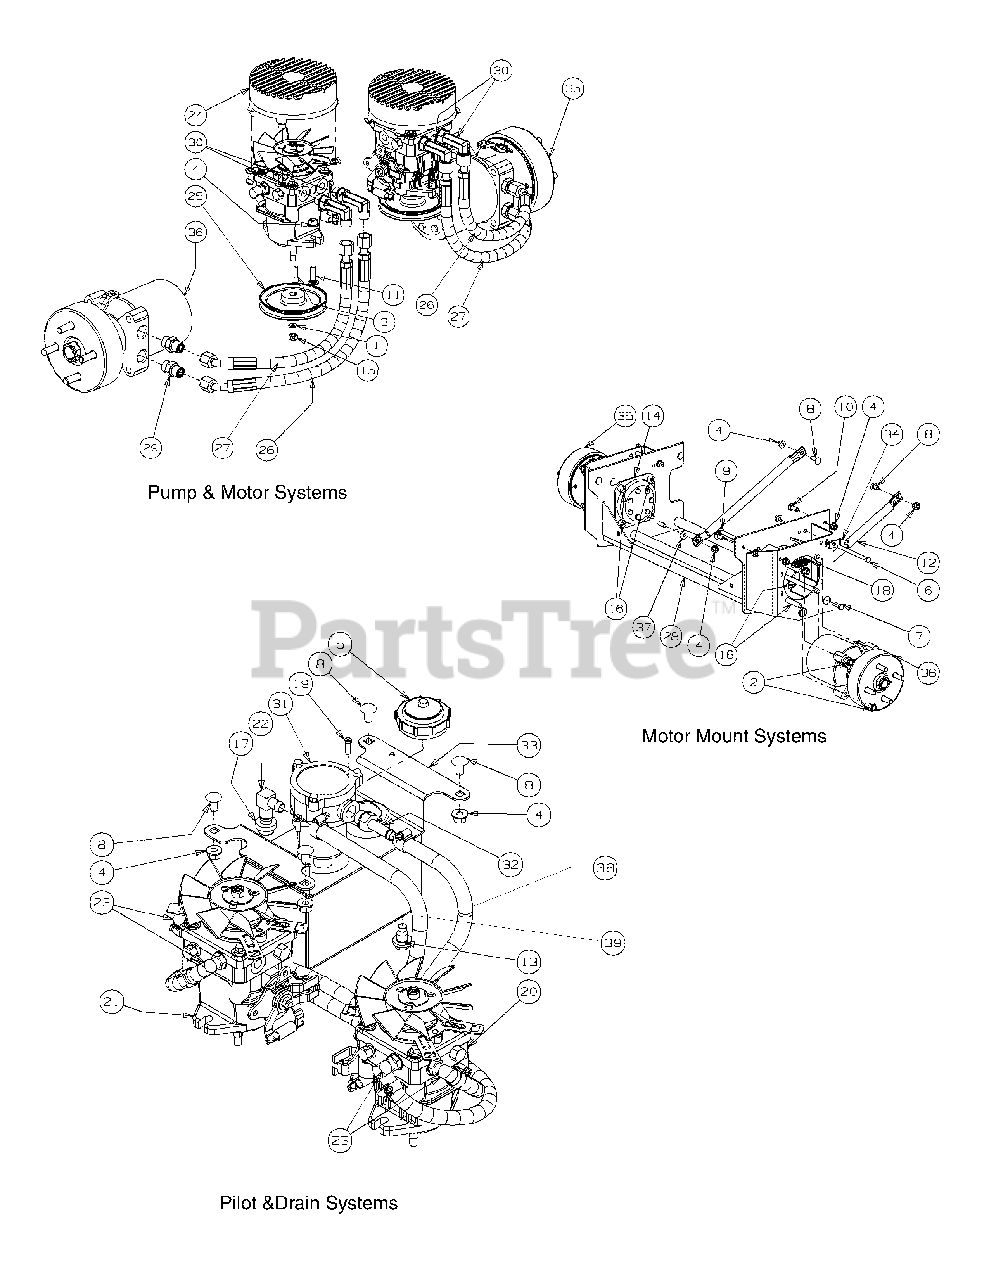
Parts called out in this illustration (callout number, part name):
1	Hose Clamp, 1/2
2	Lock Nut, Nylon Insert, 1/2-13
3	Key, 3/16" x 7/8"
4	Flange Lock Hex Nut, 3/8-16
5	Cap, Hydro Oil Tank
6	Hex Cap Screw 3/8-16 x 4.50
7	Hex Cap Screw, 3/8 -16 x 1.25
8	Carriage Bolt, 3/8-16 x .75 LG.
9	Carriage Bolt, 3/8-16 x 5.00
10	Carriage Bolt, 3/8-16 x 1
11	Carriage Screw, 3/8-16 x 1.25
14	Hydro Wheel Motor Backup Plate
15	Hex Nut, 3/8-24
16	Socket Head Capscrew, 1/2-13; 6-1/2
17	Grommet Fitting, .54 ID x .78 OD
18	Spring Extension, .740 OD x 2.656
19	Socket Low Head Cap Screw, 1/4-20 x 0.75
20	Hydro Pump, BDP-12, RH
20	Kit, Fan
21	Hydro Pump, BDP-12, LH
21	Kit, Fan
22	Fitting Elbow Spur, 5/8 x 1/2
23	Fitting Elbow, 9/16 x 1/2
24	Fan Pump Shroud
25	Hydro Pump Pulley
26	Short Pressure Hose Assembly
27	Long Pressure Hose Assembly
28	Hydro Motor Frame Assembly
29	Adaptor Fitting, 8 x 10
30	Adaptor, 8 x 8
31	Hydraulic In-Tank Filter includes:
31	Replacement Filter
32	Fitting, 3/4 ORB x 1/2 Tube
33	Hydraulic Tank Assembly
34	Rear Cable Mounting Bracket
35	Hydro Motor, Left Hand Assembly w/ Brake & Drum
36	Hydro Motor, Right Hand Assembly w/ Brake & Drum
37	Idler Washer
38	Hose Assembly, Pilot Includes:
38	Tee Fitting, 1/2
38	Hose Clamp, 1/2
38	Fuel Hose, .50 ID x .75 OD
39	Hose Assembly, Drain Includes:
39	Tee Fitting, 1/2
39	Hose Clamp, 1/2
39	Fuel Hose, .50 ID x .75 OD
